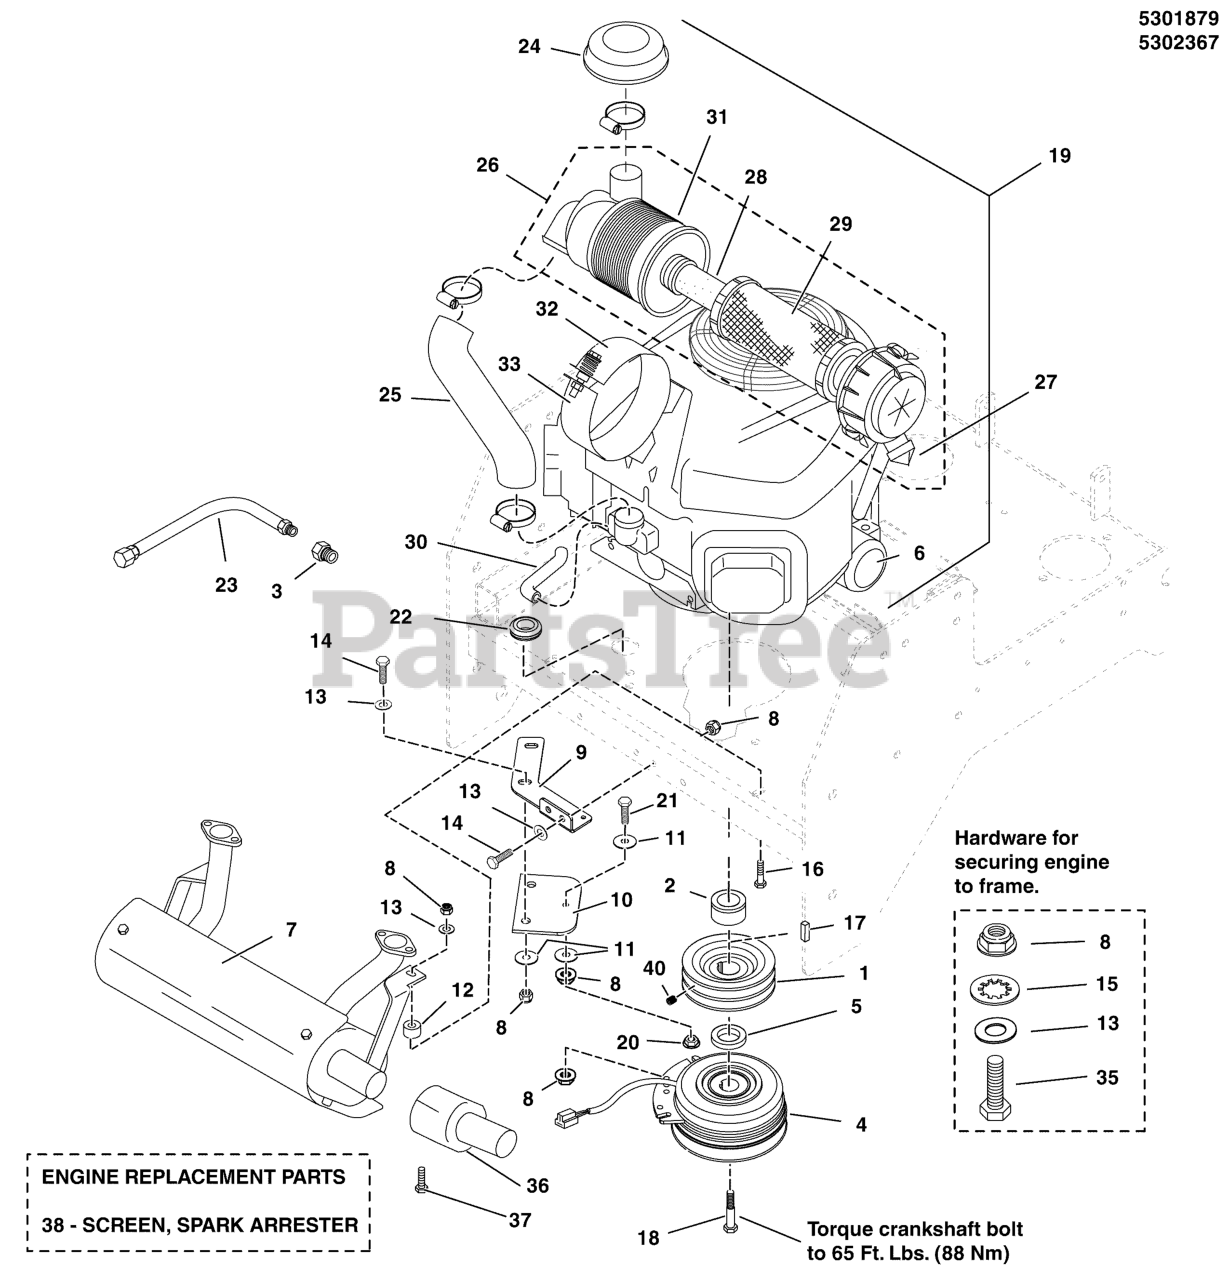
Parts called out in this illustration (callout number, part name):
1	PULLEY CRANKSHAFT (DOUBLE A)
2	SPACER, 1.13 X 1.75 X 1.03
3	ADAPTER, OIL DRAIN
4	* CLUTCH, 5218-134, WARNER
5	SPACER, 1.13 X 1.75 X .38
6	FILTER, OIL
7	MUFFLER, KAWI, HORIZONTAL, 5" CAN
8	NUT, 5/16-18 HEX NYLOCK FLANGE
9	PLATE, CLUTCH ANCHOR
10	CLUTCH ANCHOR PAD
11	WASHER, CLUTCH ANCHOR
12	SPACER, .39 X 1.00 X .80
13	WASHER, 5/16" SAE
14	BOLT, 5/16-18 X 1" GD5 YZ
15	WASHER, 5/16" INT. TOOTH LOCK
16	BOLT, 5/16-18 X 1-3/4" GD5
17	KEY, 1/4 SQ X 1
18	BOLT, CRANKSHAFT,7/16-20X2-1/2, GD8
19	ENGINE, Kawasaki
20	NUT, 5/16-18 HEX SERRATED FLANGE (LARGE)
21	BOLT, 5/16-18 X 2-1/2 GD5 TFL, CZ
22	GROMMET, 7/8
23	HOSE, OIL DRAIN
24	RAIN COVER
25	AIR INLET TUBE
26	AIR FILTER ASSEMBLY
27	RUBBER DUST VALVE
28	AIR FILTER, SECONDARY
29	AIR FILTER, PRIMARY
30	BREATHER TUBE
31	CASE, AIR FILTER
32	CASE, BRACKET, AIR FILTER
33	CASE, BRACKET, AIR FILTER
35	BOLT, HEX FLG, SER, GD5 3/8-16 X 1-1/4" PACH CZ
36	EXTENSION, TAILPIPE, 3" - BLACK
37	SCREW, SELF-TAP, #8-32 X 3/8, WASH HEX, CZ
38	SCREEN, SPARK ARRESTER
40	SET SCREW, 5/16-18 X 3/8, KNURL W/PATCH
